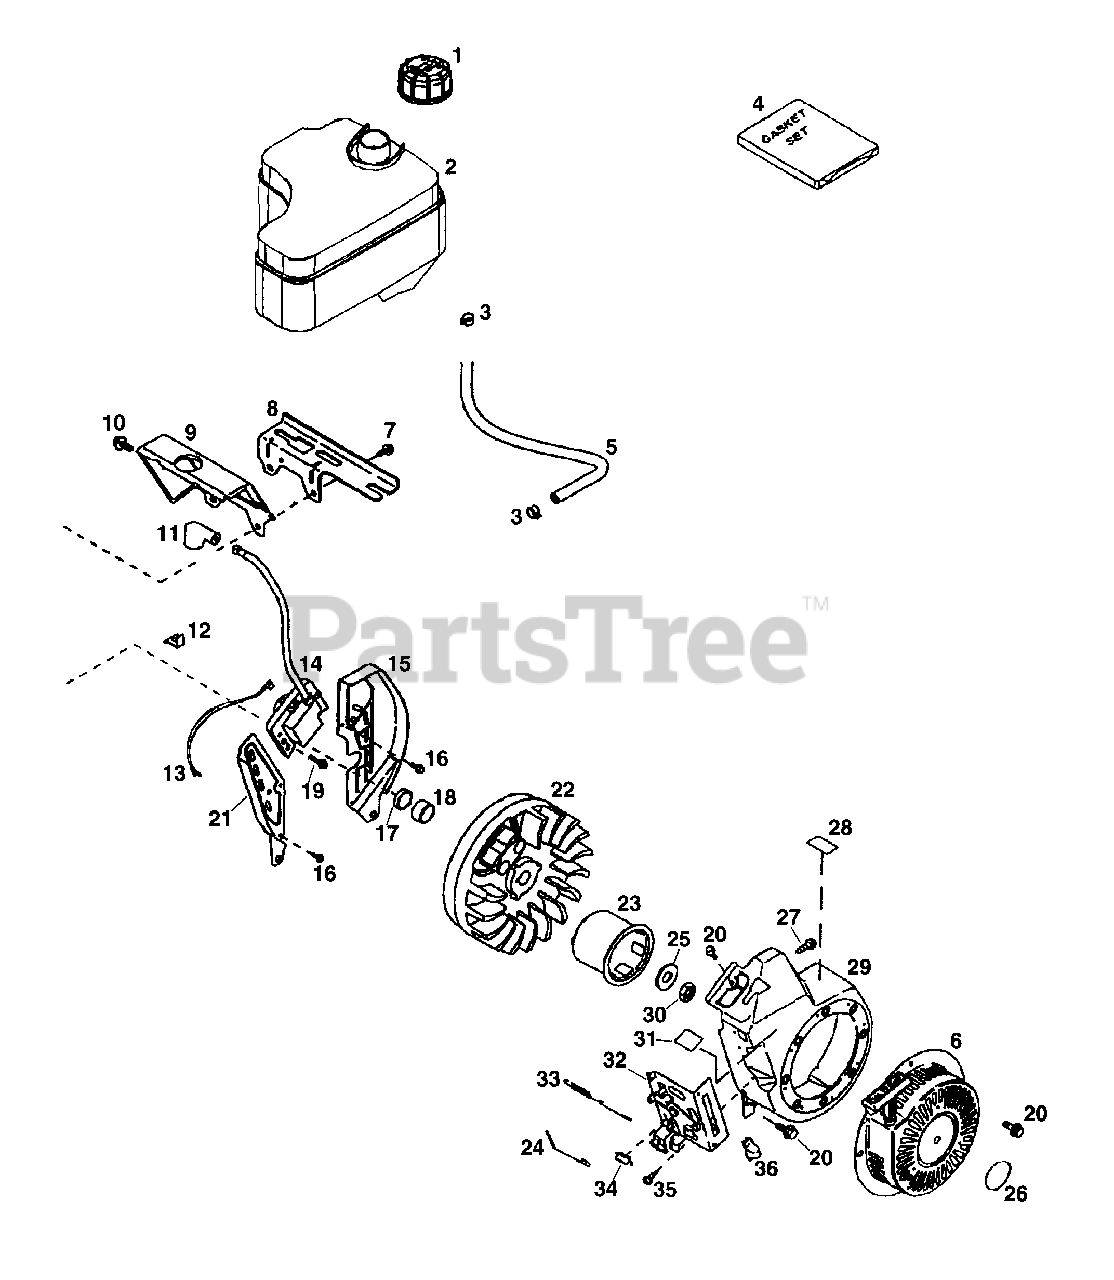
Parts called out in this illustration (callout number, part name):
1	Fuel Cap
2	Fuel Tank
3	Fuel Line Clamp
4	Gasket Set
5	Fuel Line
6	Rewind Starter
7	Screw, 1/4-20 x 7/8"
8	Fuel Tank Bracket
9	Blower Housing Extension
10	Screw, 10-24 x 9/16"
11	Spark Plug Cover
12	Wire Clip
13	Ground Wire
14	Solid State Ignition
15	Air Baffle (Right)
16	Screw, 10-24 x 9/16"
19	Screw, Torx T 15, 15/16"
20	Screw, 1/4-20 x 31/64"
21	Air Baffle (Left)
23	Starter Cup
24	Governor Link
25	Bell Washer
26	Starter Decal
27	Screw, 10-32 x 1/2"
28	Lube Decal
29	Blower Housing
30	Flywheel Nut
31	Speed Control Decal
32	Control Bracket
33	Extension Spring
35	Screw, 10-32 x 1/2"
36	Control Knob
